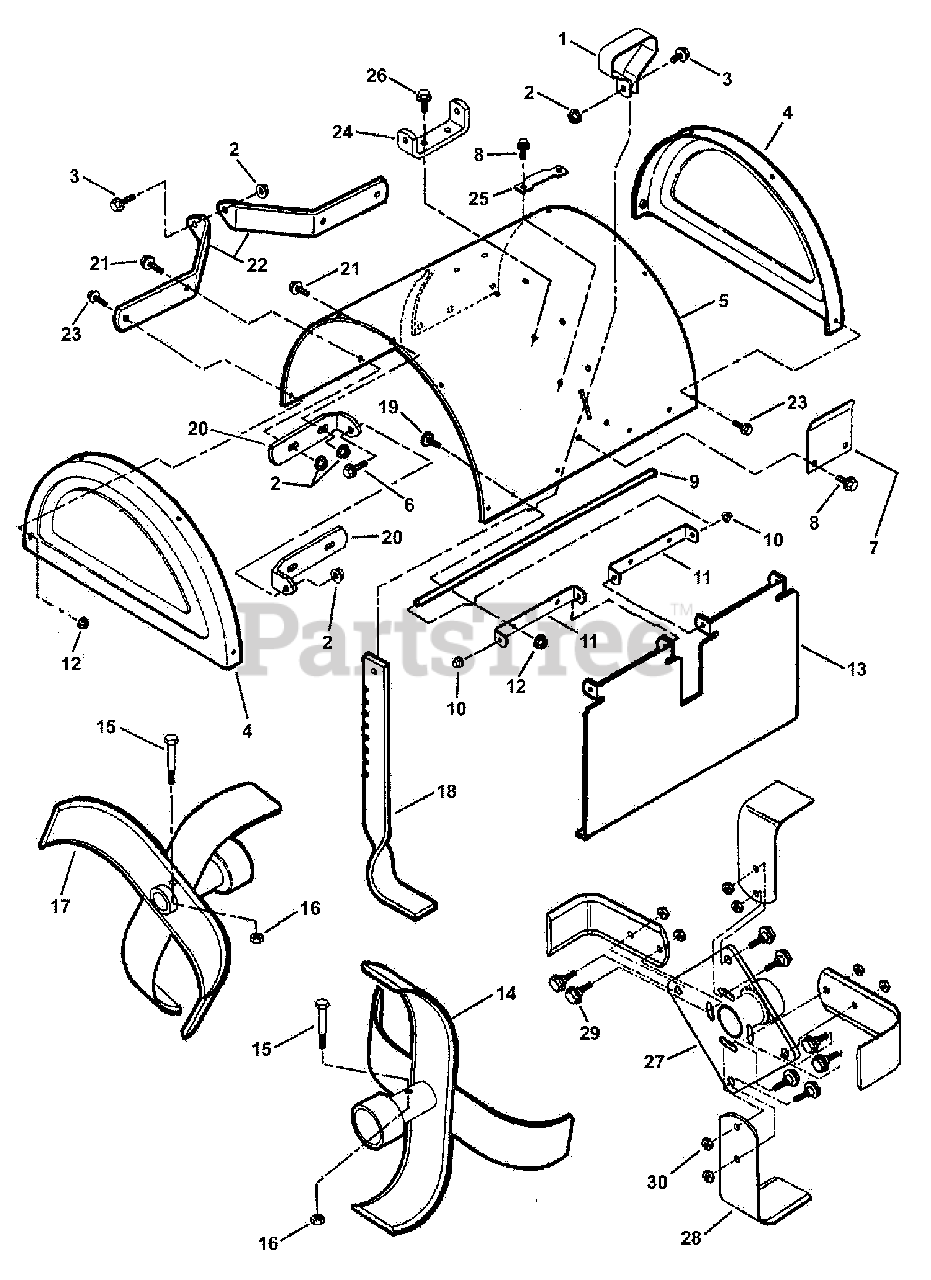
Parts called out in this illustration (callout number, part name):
1	HANDLE, Depth Bar
2	NUT, 5/16-18 Hex Flange Lock
3	BOLT, 5/16-18 x 1" Hex Flange Lock
4	COVER, Side Tine IR5003B
5	COVER, Tine IR5003B
6	BOLT, 5/16-18 x 1-1/2" Hex Flange Lock GR5
7	SPRING, Depth Bar IR5003B
8	SCREW, 5/16-18 x 5/8" Hex Washer Self-Tap
9	PIN, Drag Shield (1/4" Dia. x 14-1/2" Steel Rod)
10	PUSHNUT, 1/4"
11	HINGE, Half
12	NUT, 1/4-20 Hex Flange Lock
13	SHIELD, Drag
14	WELDMENT, Right Tine
15	SCREW, 5/16-24 x 2" Hex Head Cap GR5
16	NUT, 5/16-24 Hex Center Lock
17	WELDMENT, Left Tine
18	DEPTH-BAR
19	BOLT, 1/4-20 x 1/2" Short Neck Carriage GR5
20	REINFORCEMENT, Rear Tine Cover
21	BOLT, 5/16-18 x 5/8" Hex Flange Lock GR5
22	REINFORCEMENT, Front Tine Cover
23	SCREW, 1/4-20 x 3/4" Hex Washer Self-Tap
24	BRACKET, Support IR5003B
25	PLATE, Latch
26	SCREW, 5/16-18 x 1" Hex Washer Self-Tap
27	WELDMENT, Tine Hub ICFR
28	TINE, 11.5" (.312" Thick)
29	BOLT, 3/8-24 Shoulder
30	NUT, 3/8-24 Hex Top Lock GR C
